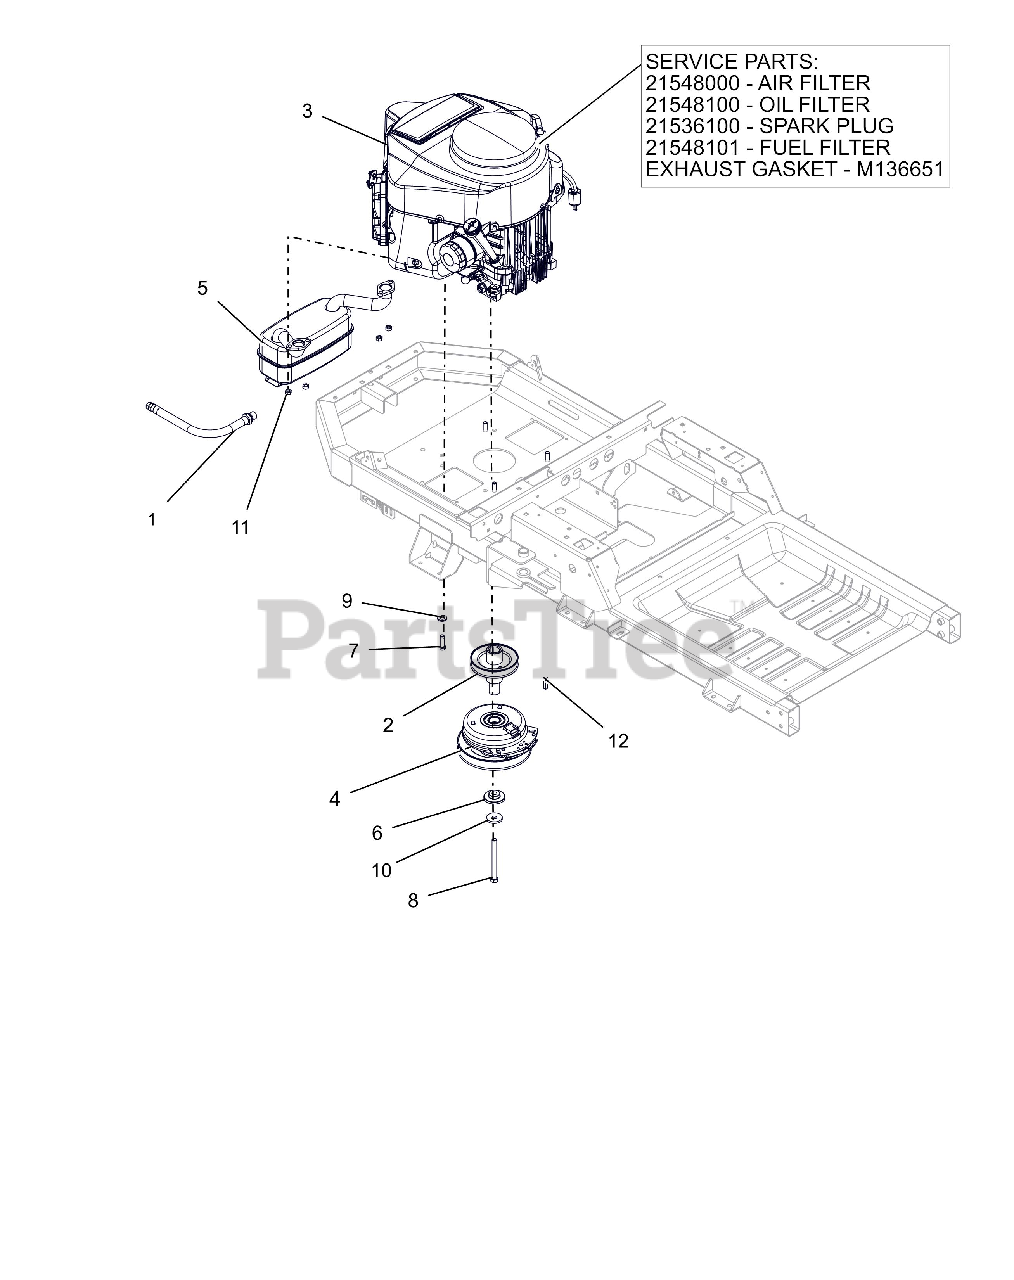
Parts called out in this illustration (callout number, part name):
1	HOSE, OIL DRAIN
2	WLDMT, DRIVE SHEAVE-X
3	AIR FILTER, KAWASAKI FR
3	OIL FILTER, KAWASAKI FR
3	PLUG, SPARK
3	FUEL FILTER-KAWASAKI FR
3	GASKET, MUFFLER #
4	CLUTCH,105FTLB MONOPOLE 6.83"
5	MUFFLER - KAWASAKI
6	BSHG-FLG .469X1.06X.574X2.0
7	BLT-HEX.38-16X1.25 G5YZ NYTORQ
8	BLT-HEX.438-20X4.5GR8YZ NYTORQ
9	WASHER, 3/8" SPRING DISC
10	WASHER, 7/16" SPRING DISK
11	NUT-LK-TOP M8-1.25 YWZC
12	KEY-SQ .25 X 1.25 X .25 SAE
